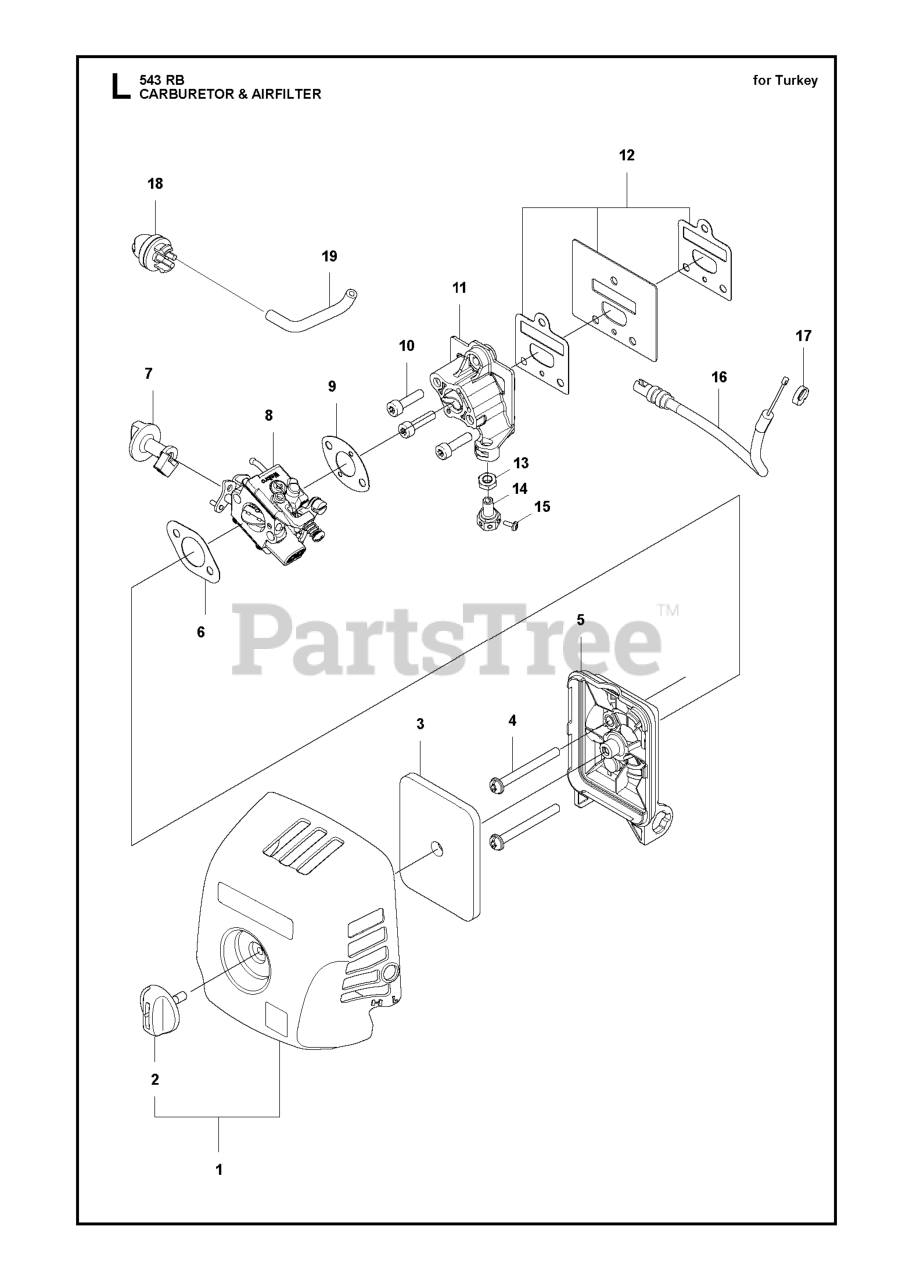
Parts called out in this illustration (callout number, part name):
2	TURNING KNOB GZ40N7
3	ELEMENT
4	BOLT TORX
5	HOUSING
6	GASKET
7	KNOB
8	Carburetors
9	GASKET
10	BOLT TORX
11	INSULATOR
12	GASKET, INSULATOR
13	NUT
15	SCREW
17	CAP
18	PRIMARY BTN
19	PIPE L70
